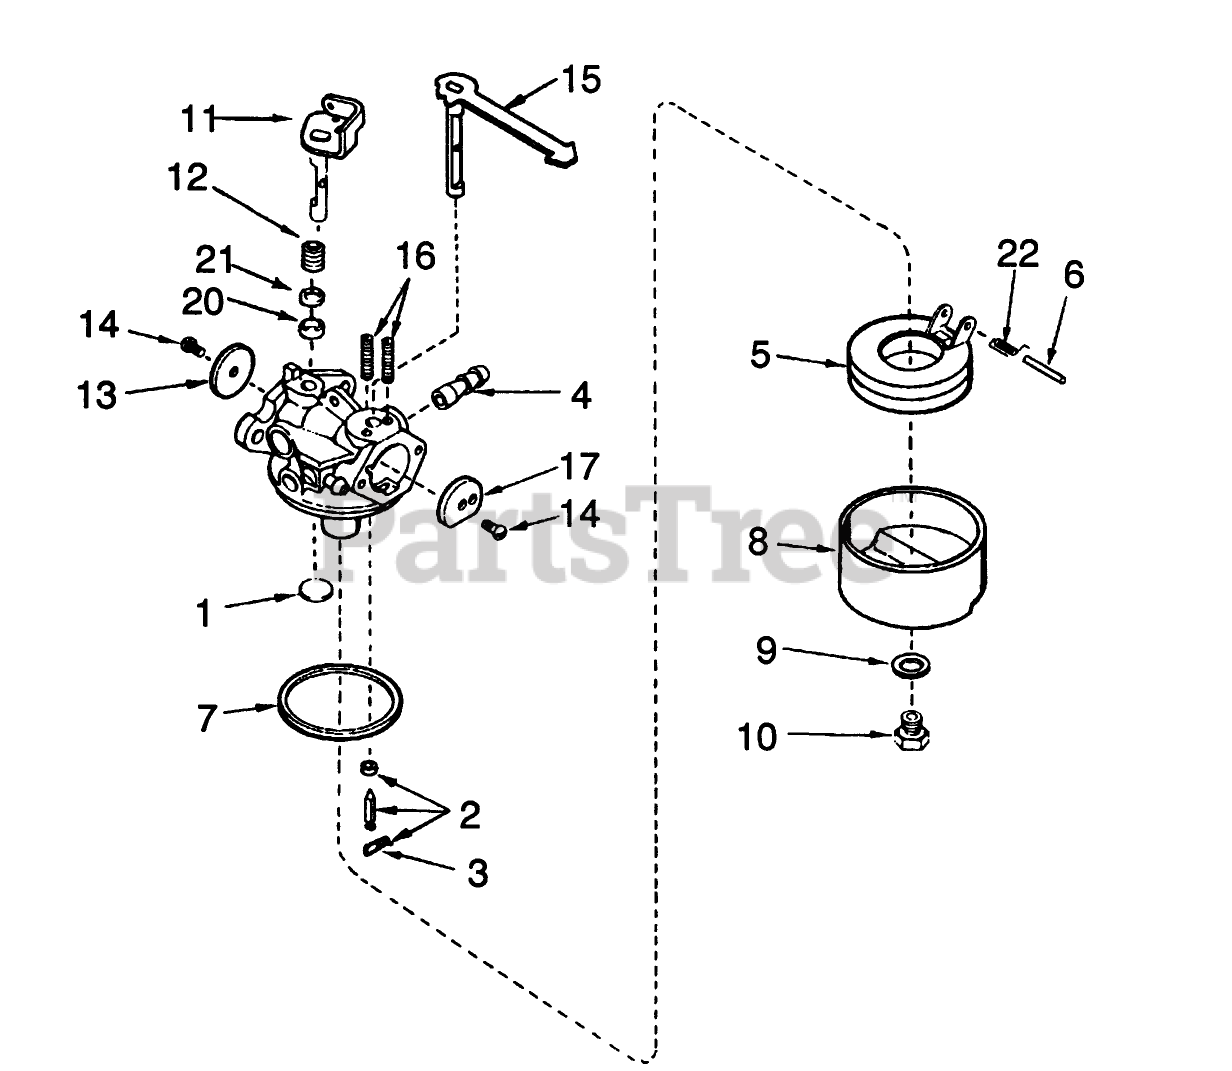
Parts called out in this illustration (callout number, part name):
1	Plug-Welch, Atmospheric Vent
2	Inlet Needle, Seat Clip Assy. (Incl. No. 13)
3	Clip-Spring
4	Fitting-Fuel
5	Float
6	Shaft-Float
7	O Ring-Bowl, Float
8	Bowl Float
9	Gasket-Bowl
10	Nut-Float Bowl
11	Shaft/Lever-Throttle
12	Spring-Trottle, Return
13	Shutter-Throttle
14	Screw-Shutter
15	Choke Shaft Lever Assy.
16	Spring-Positioning, Choke
17	Shutter-choke
20	Seal-Dust
21	Washer-Seal, Dust
22	Spring-Float, Dampening
